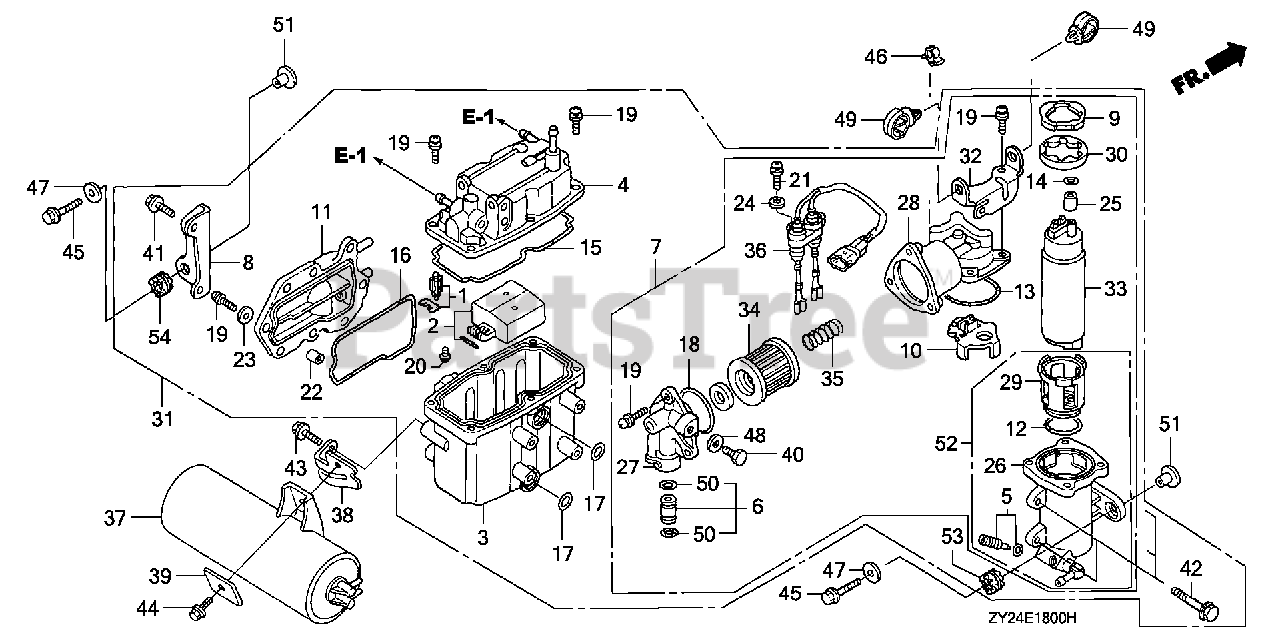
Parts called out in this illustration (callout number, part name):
1	VALVE SET, FLOAT
3	BODY
5	SCREW SET, DRAIN
7	PUMP UNIT, FUEL (MSDS)
8	STAY, PLATE
11	COVER, WATER JACKET
14	O-RING
19	SCREW-WASHER
20	SCREW, PAN
21	SCREW, WASHER
22	COLLAR, SET
23	WASHER, PLAIN
24	WASHER, PLAIN
26	CASE, PUMP
27	COVER, PUMP
28	COVER, PUMP
29	INSULATOR, FUEL PUMP
31	SEPARATOR ASSY., VAPOR
32	STAY, PLATE
33	PUMP UNIT, FUEL (MSDS)
34	SCREEN, FUEL STRAINER
35	SPRING, SET
37	TANK, VACUUM
38	STAY, VACUUM TANK
40	BOLT, SEALING (6MM)
41	BOLT, FLANGE (6X16)
42	BOLT, FLANGE (6X25)
43	BOLT, FLANGE (6X14)
44	BOLT, FLANGE (6X12)
45	BOLT, FLANGE (8X35)
46	HOLDER, ROD (6MM)
47	WASHER, PLAIN (8MM)
48	WASHER, SEALING (6MM)
49	CLIP, HARNESS
50	O-RING (7.8X1.9) (ARAI)
51	COLLAR (8.5X14.5)
52	PUMP UNIT, FUEL (MSDS)
53	GROMMET, VAPOR SEPARATOR
54	GROMMET, VAPOR SEPARATOR
